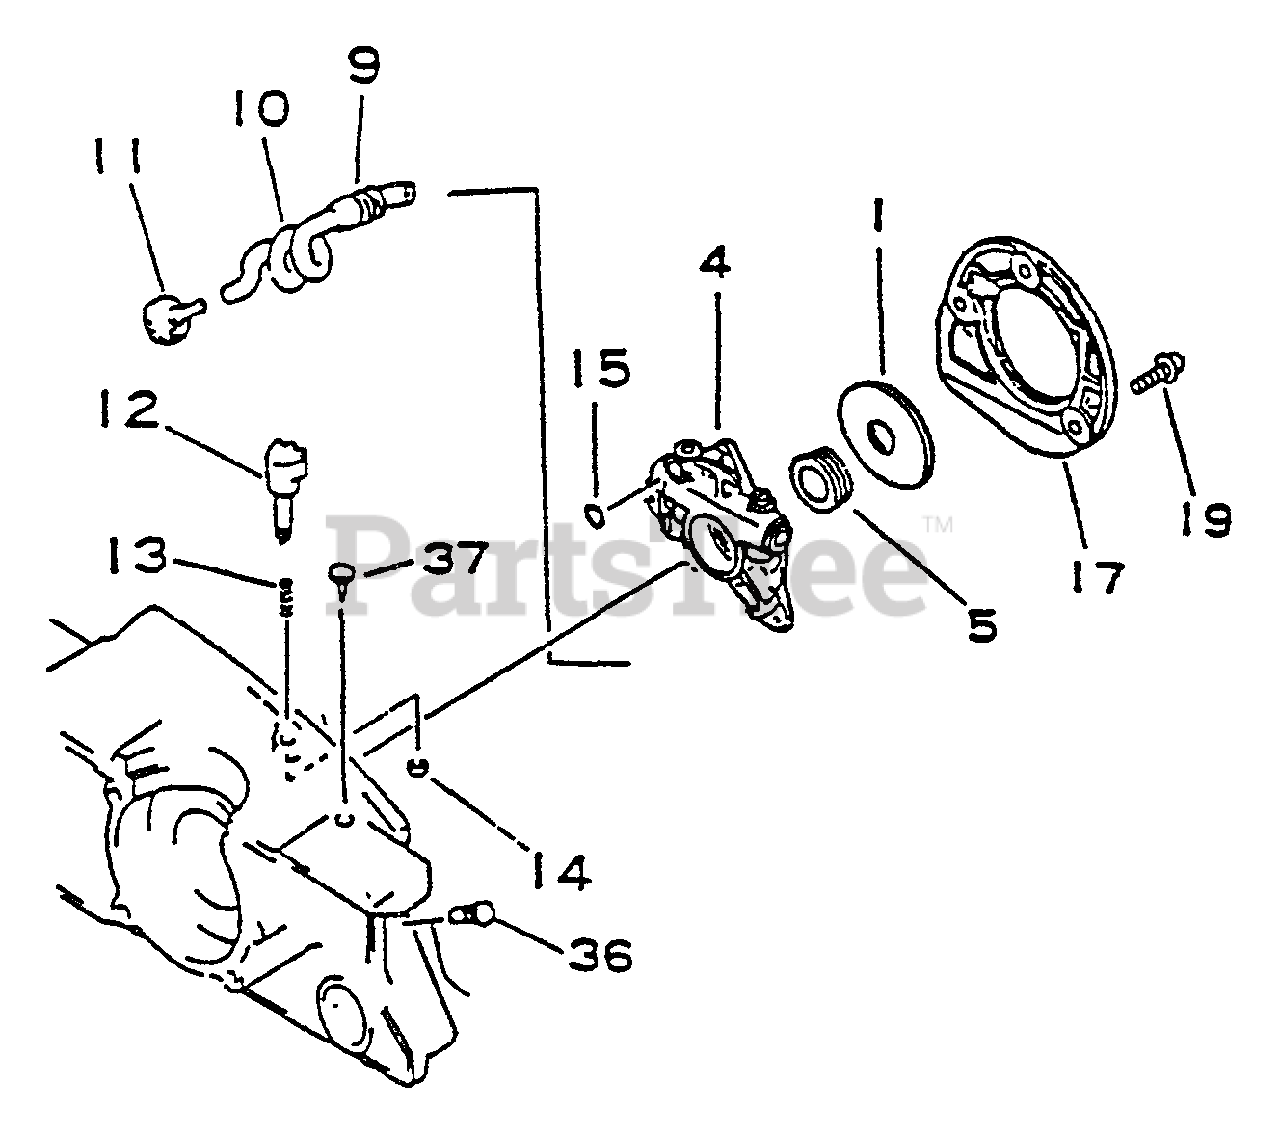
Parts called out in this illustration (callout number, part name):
1	GEAR - WORM
4	AUTO-OILER ASSY
5	GEAR - WORM
10	PIPE - OIL
11	FILTER, OIL
12	DIAL, AUTO-OILER
14	RING, RETAINING - 3
15	O-RING - 3
17	COVER, OIL PUMP
19	SCREW - 4X14
36	PLUG
